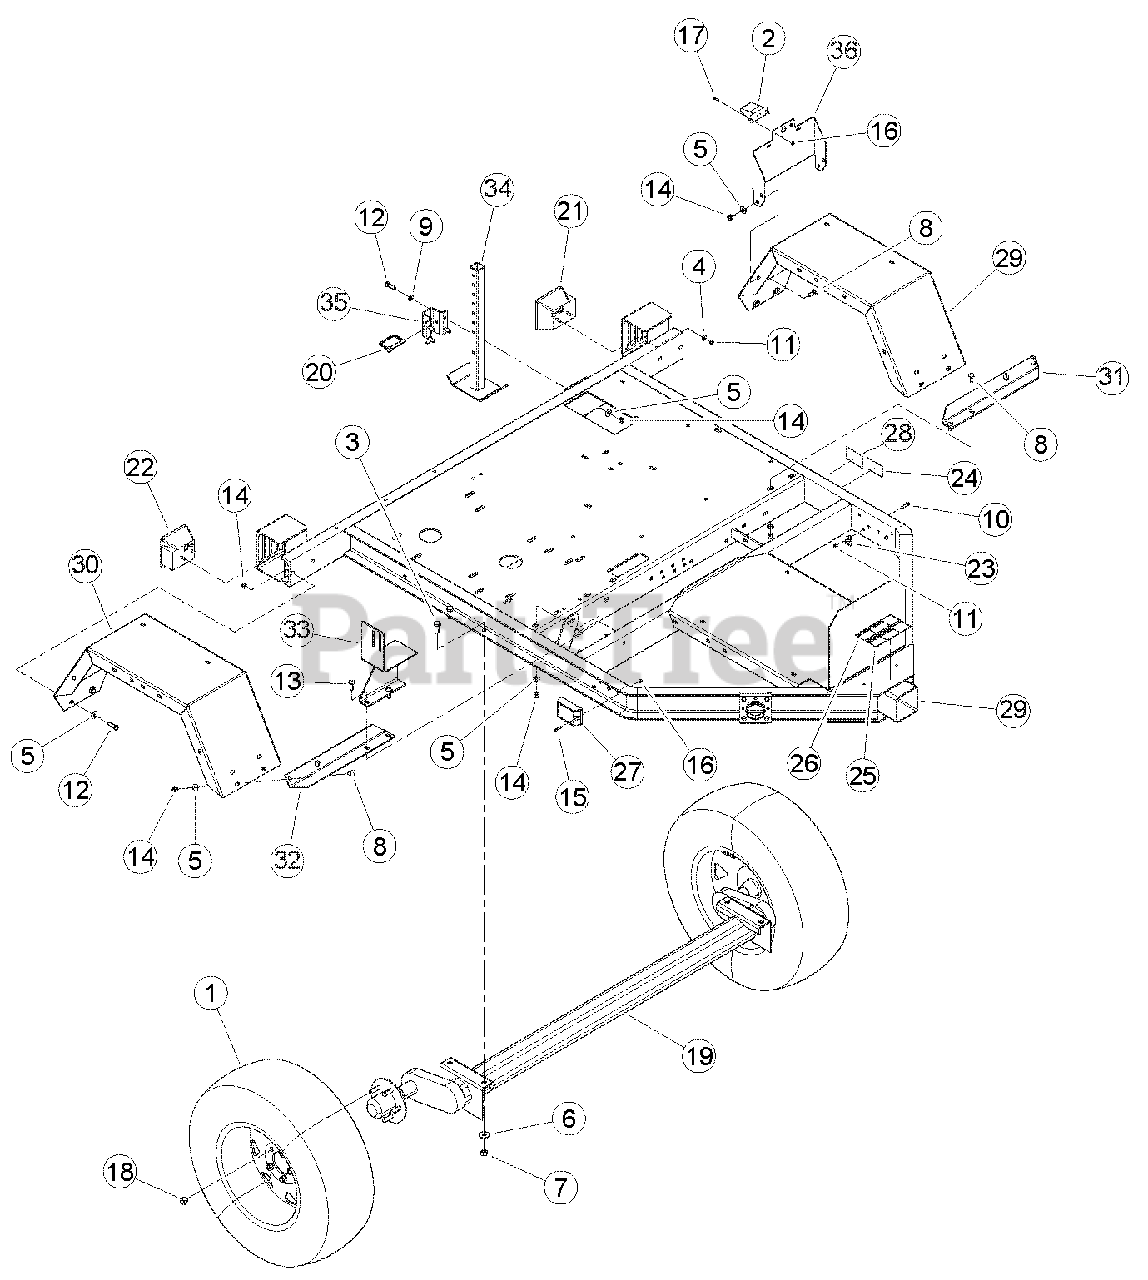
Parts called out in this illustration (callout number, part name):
1	ASSEMBLY, 15 IN. TIRE & WHEEL
2	LIGHT, LICENSE PLATE
3	BOLT, 1/2 X 1-1/4 HEX GR5 NC ZP
4	WASHER, 1/4 FLAT ZP
5	WASHER, 3/8 FLAT ZP
6	WASHER, 1/2 FLAT ZP
7	NUT, 1/2 CENTERLOCK GRB ZP
8	BOLT, 3/8 X 1 CRG GR5 NC ZP
9	WASHER, 3/8 SAE FLAT ZP
10	BOLT, 1/4 X 1 HEX GR8 ZP
11	NUT, 1/4 NE NYLOCK ZP
12	BOLT, 3/8 X 1-1/4 HEX GR5 ZP
13	BOLT, 3/8 X 1-1/4 CRG GR5 NC ZP
14	NUT, 3/8 NE NYLOCK ZP
15	MACH. SCREW,10-24 X 1 RND HD PHL ZP
16	NUT, 10/24 NYLOCK TYPE NM ZP
17	MACH. SCREW, #10-24 X 3/4 PAN HD PH ZP
18	NUT, 1/2 -20 WHEEL
19	AXLE, 3000 LB. TORSION
20	PIN, 3/8 X 2-3/4 SNAP
21	LIGHT, LH TAIL
22	LIGHT, RH TAIL
23	CLAMP, CABLE MOUNT
24	DECAL, P215/70R15 LOAD RATING
25	DECAL, TRAILER ELECTRICAL
26	DECAL, CHECK WHEELS
27	LIGHT, AMBER SIDE MARKER
28	DECAL, EPA EMISSION
29	WELDMENT, CHIPPER TRAILER
30	FENDER, HEAVY DUTY
31	ANGLE, FENDER MOUNT LH
32	ANGLE, FENDER MOUNT RH
33	WELDMENT, BELT GUIDE
34	WELDMENT, REAR STABILIZER
35	GUIDE, TRAILER SUPPORT
36	BRACKET, LICENSE PLATE
